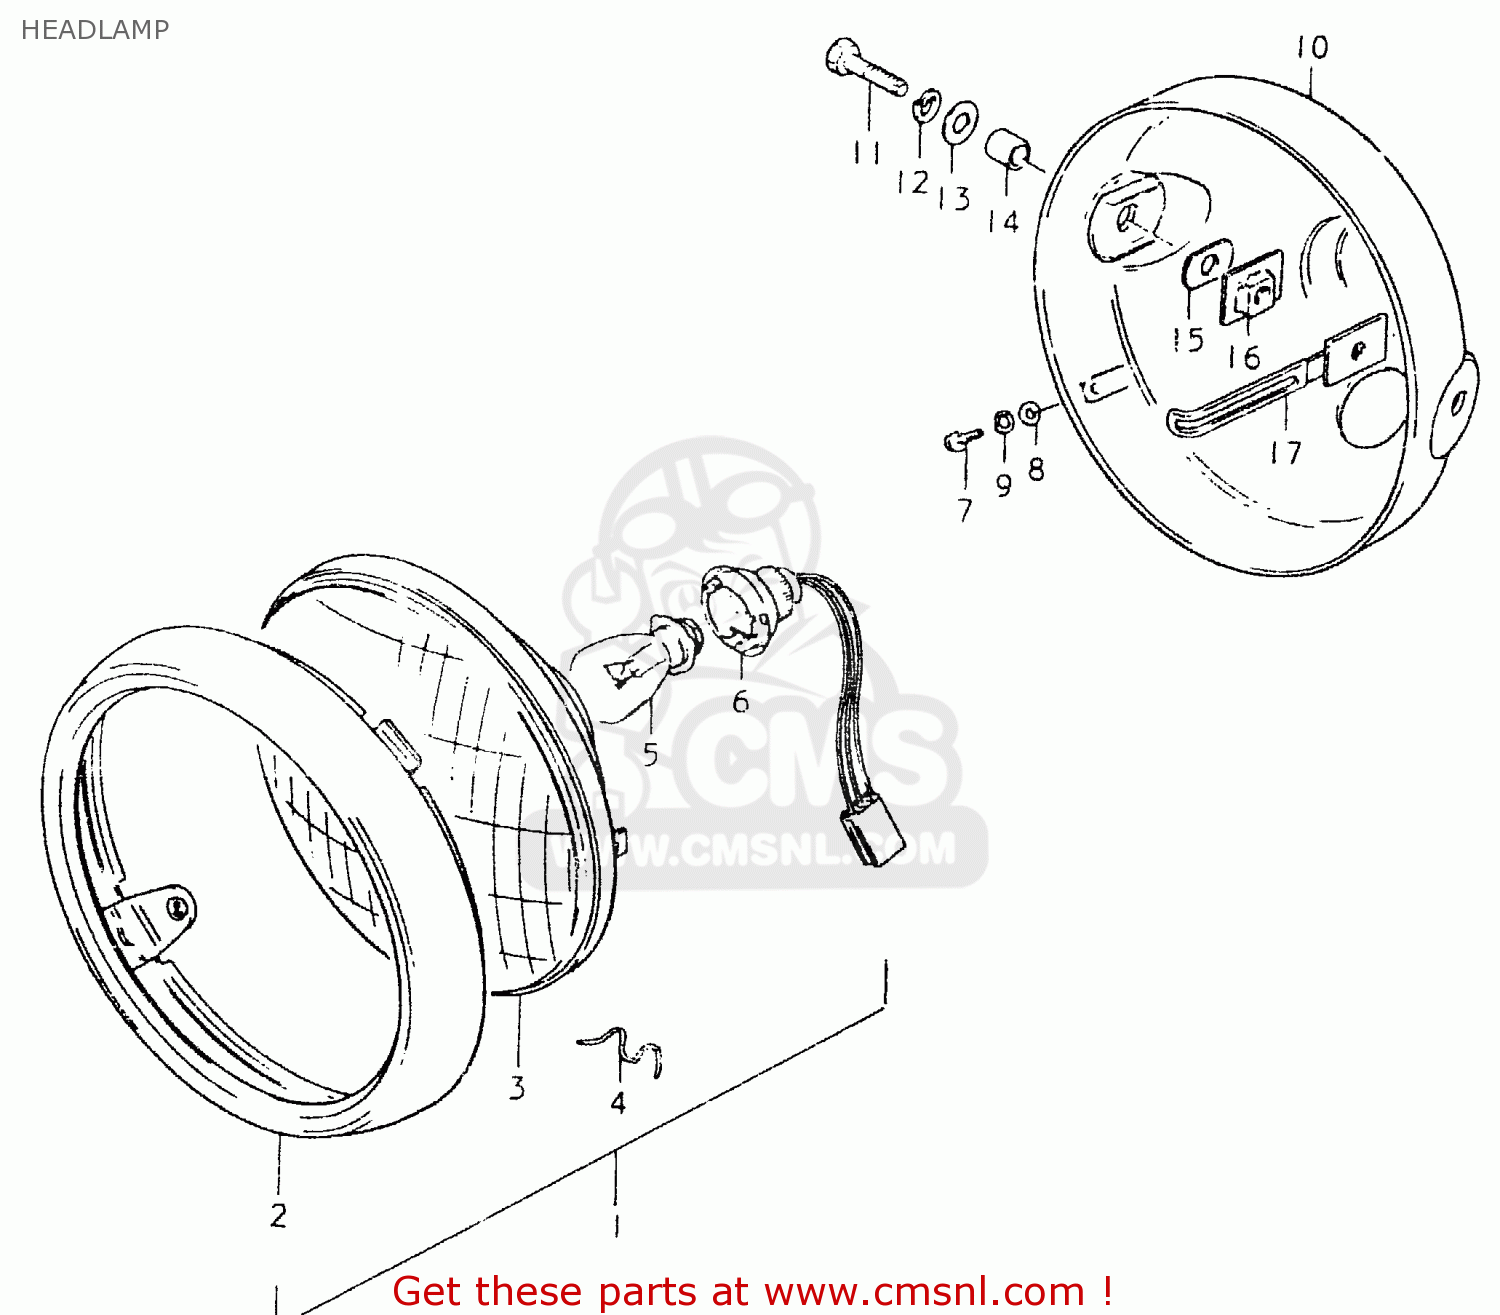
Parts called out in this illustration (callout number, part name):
1	HEADLAMP ASSY
2	RIM
3	UINT
4	SPRING
5	BULB(6V,35/35W)
6	SOCKET
7	SCREW
8	WASHER
9	LOCK WASHER
10	HOUSING,HEADLAMP
11	BOLT
12	LOCK WASHER
13	WASHER
14	SPACER (8.8X12X7)
15	CUSHION
16	PLATE,HEADLAMP HOUSING
17	PLATE,HEADLAMP HOUSING
